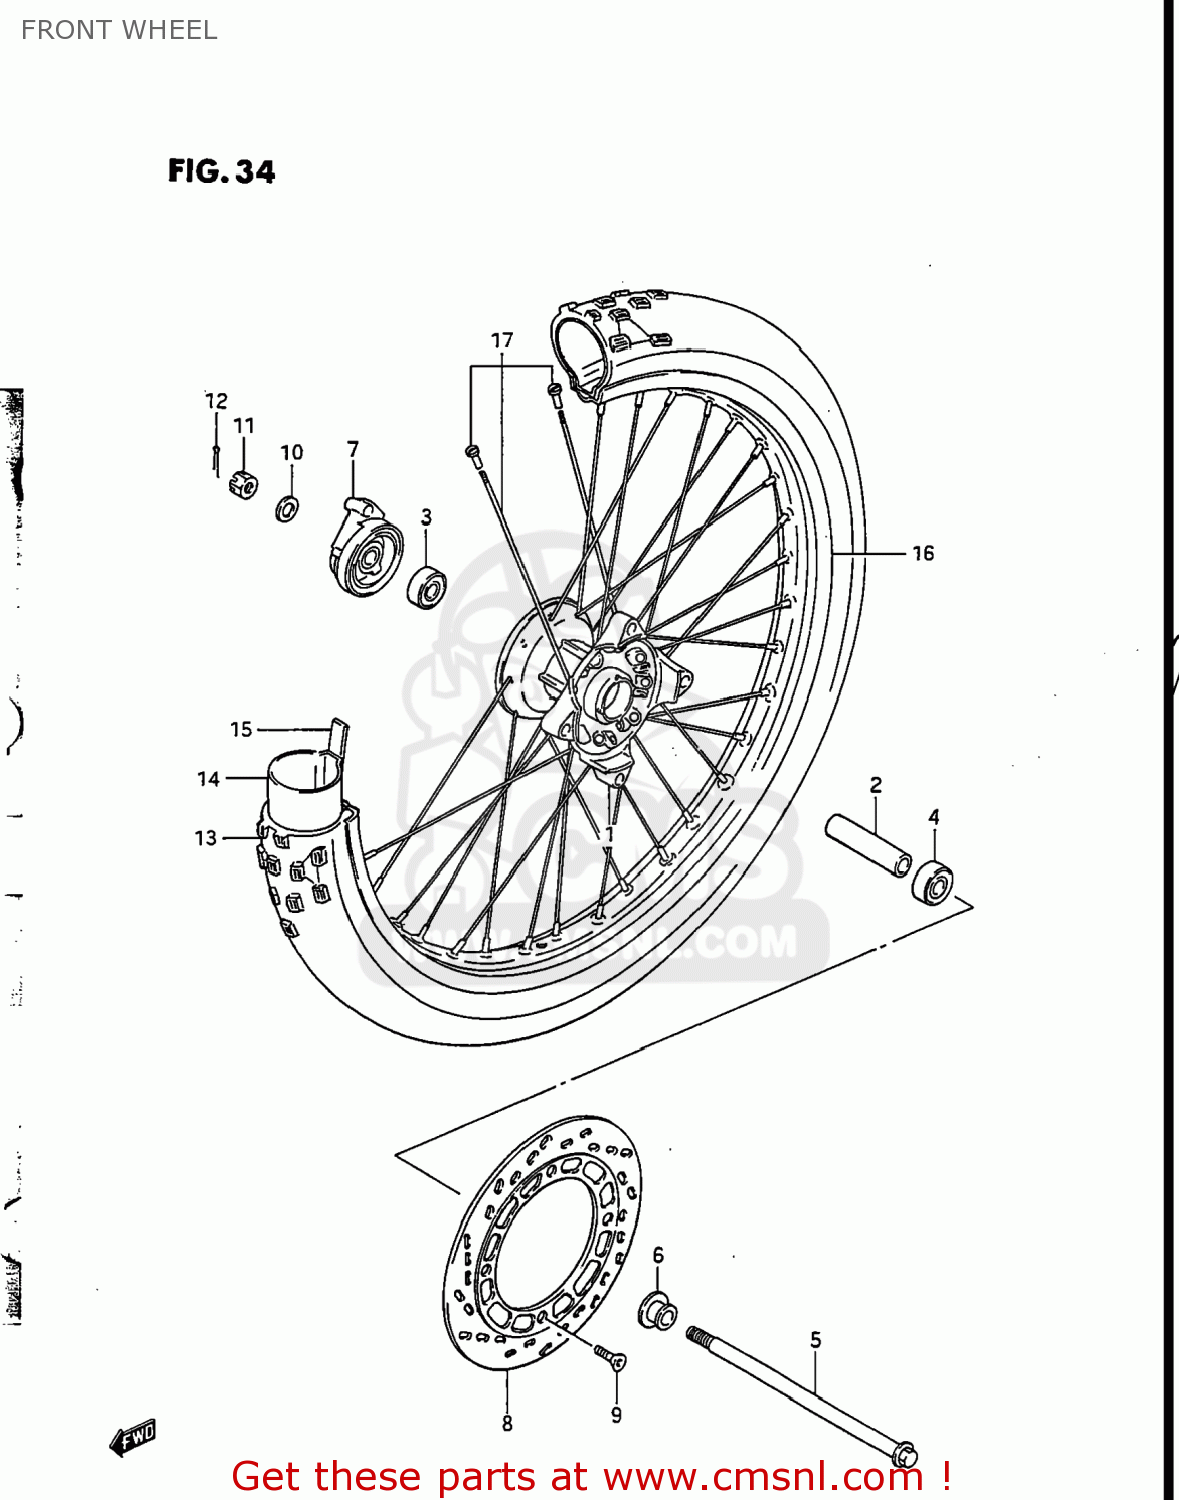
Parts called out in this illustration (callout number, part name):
1	HUB,FRONT
2	SPACER (12.6X19X60.5)
3	BEARING
4	BEARING (12X32X10)
5	AXLE,FRONT
6	SPACER,FRONT AXLE,RIGHT
7	BOX ASSY,SPEEDOMETER GEAR
8	DISC,BRAKE
9	BOLT,BRAKE DISC
10	WASHER
11	NUT 12MM
12	COTTER PIN
13	TIRE,FRONT 70/100-21
14	TUBE
15	PROTECTOR,WHEEL,INNER
16	RIM,FRONT WHEEL
17	SPOKE SET,FR WHEEL
